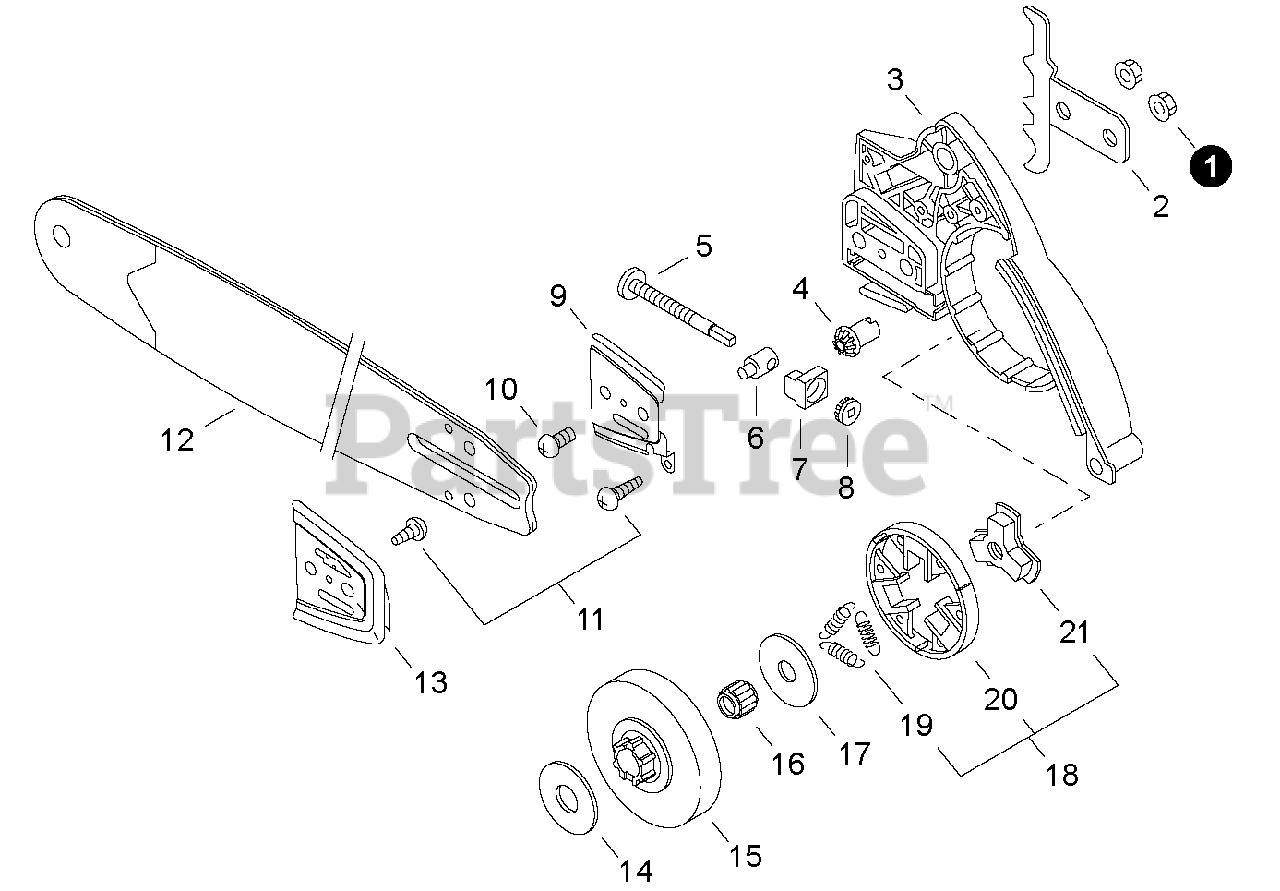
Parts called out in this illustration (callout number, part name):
1	NUT, FLANGE M8×1.25
2	SPIKE, BUMPER
3	GUARD, SPROCKET
4	GEAR, BEVEL
5	SCREW, CHAIN TENSION
6	TENSIONER, CHAIN
7	COLLAR 8
8	GEAR, BEVEL
9	PLATE, GUIDE - OUTER
10	SCREW 3×5
11	SCREW 4×10
12	GUIDE BAR, 38RD58-325
13	PLATE, GUIDE - INNER
14	PLATE, CLUTCH
15	DRUM, CLUTCH
16	BEARING, NEEDLE 10
17	PLATE, CLUTCH
18	CLUTCH ASSY
19	SPRING, TENSION
20	SHOE SET, CLUTCH (3PCS)
21	HUB, CLUTCH
